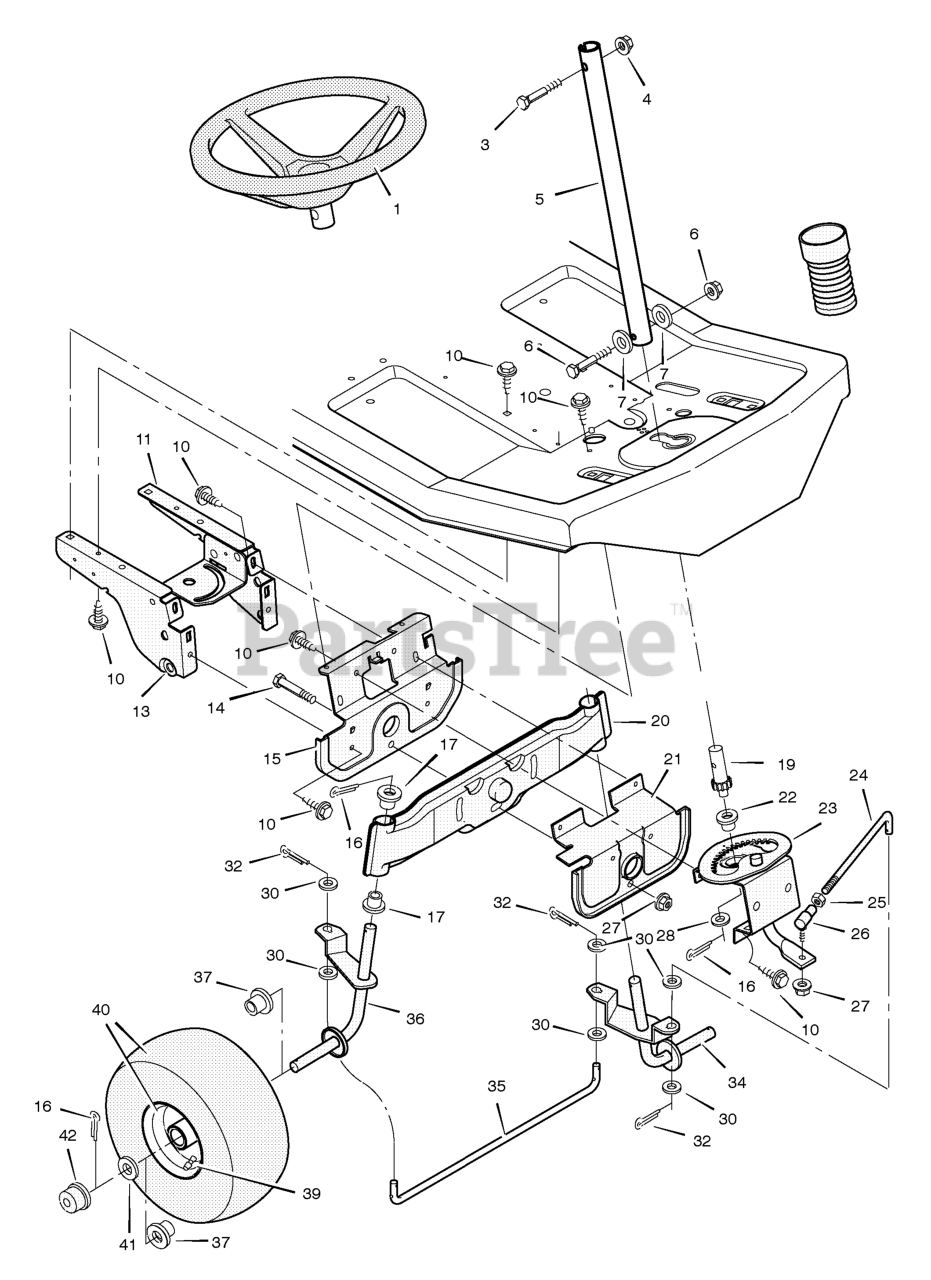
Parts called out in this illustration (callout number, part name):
1	Steering Wheel
3	Bolt, Hex
4	Locknut, Flange
5	Post, Steering
6	Nut, Hex
7	Washer
11	Plate, Left Suspension
13	Plate, Right Suspension
14	Bolt, Hex
15	Support, Front Axle
16	Pin, Cotter
17	Bearing, Spindle
19	Gear, Pinion
20	Axle Assembly, Front
21	Hanger Assembly, Front Axle
22	Bearing
23	Sector Assembly
24	Rod, Drag Link
25	Ball Joint, Steering
26	Nut, Hex
27	Locknut, Flange
28	Washer
30	Washer
32	Pin, Cotter
34	Spindle Assembly, Left
35	Rod, Tie
36	Spindle Assembly, Right
37	Bearing, Wheel
39	Valve Stem
40	Wheel & Tire Assembly
42	Cap, Hub
